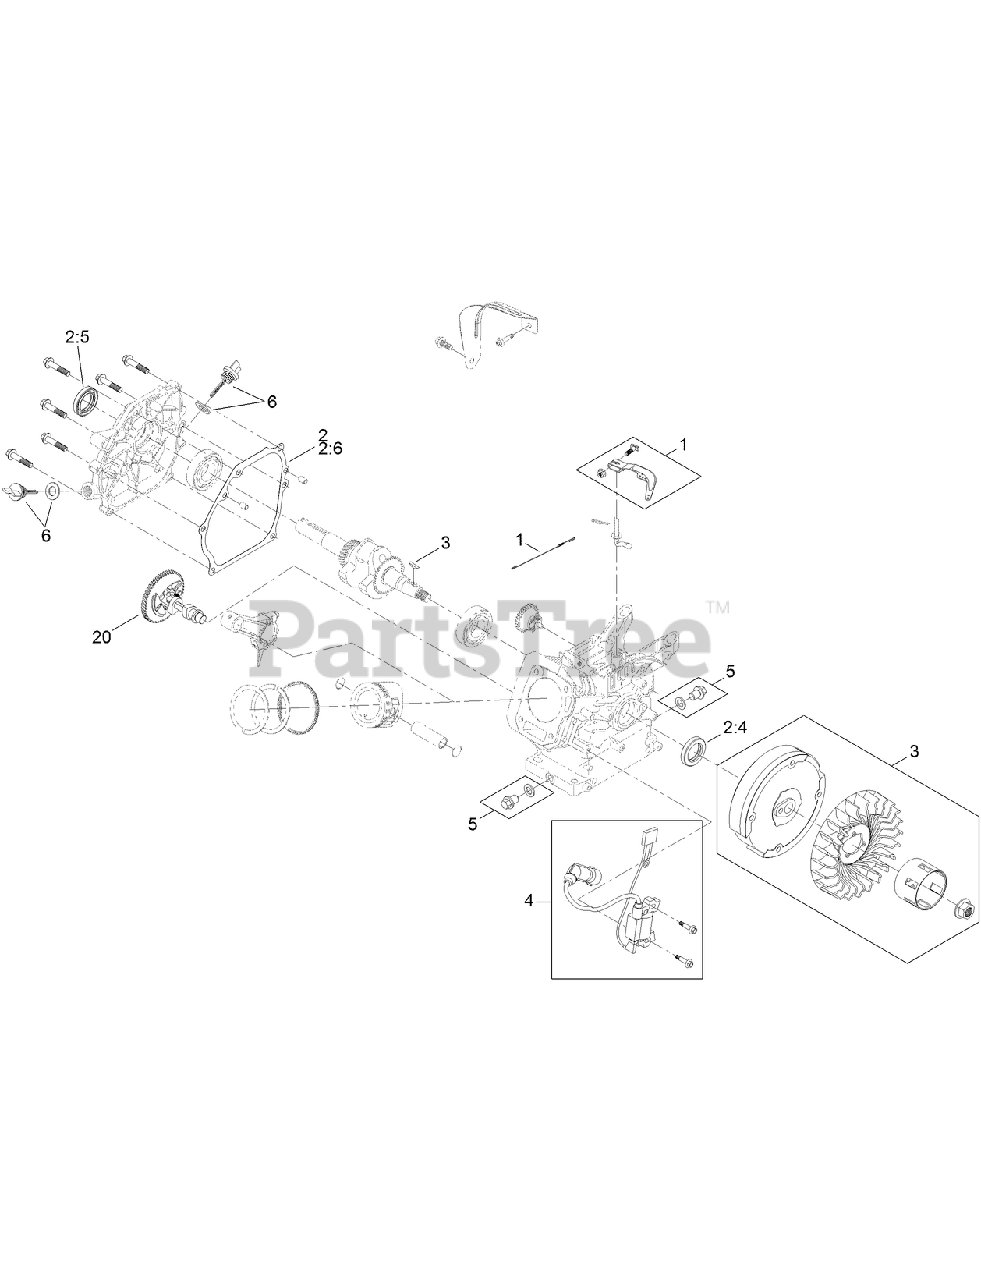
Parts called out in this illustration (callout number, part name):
1	GOVERNOR KIT
2	GASKET AND SEAL KIT
2:2	Gasket-Exhaust
2:3	GASKET-HEAD, CYLINDER
2:4	Loose Parts Package
2:5	Loose Parts Package
2:6	GASKET-COVER, CRANKCASE
2:7	GASKET-CARBURETOR
2:8	GASKET-CARBURETOR
2:9	GASKET-CARBURETOR
3	RECOIL FLYWHEEL KIT
5	DRAIN PLUG KIT
6	DIPSTICK AND O-RING KIT
20	CAMSHAFT
